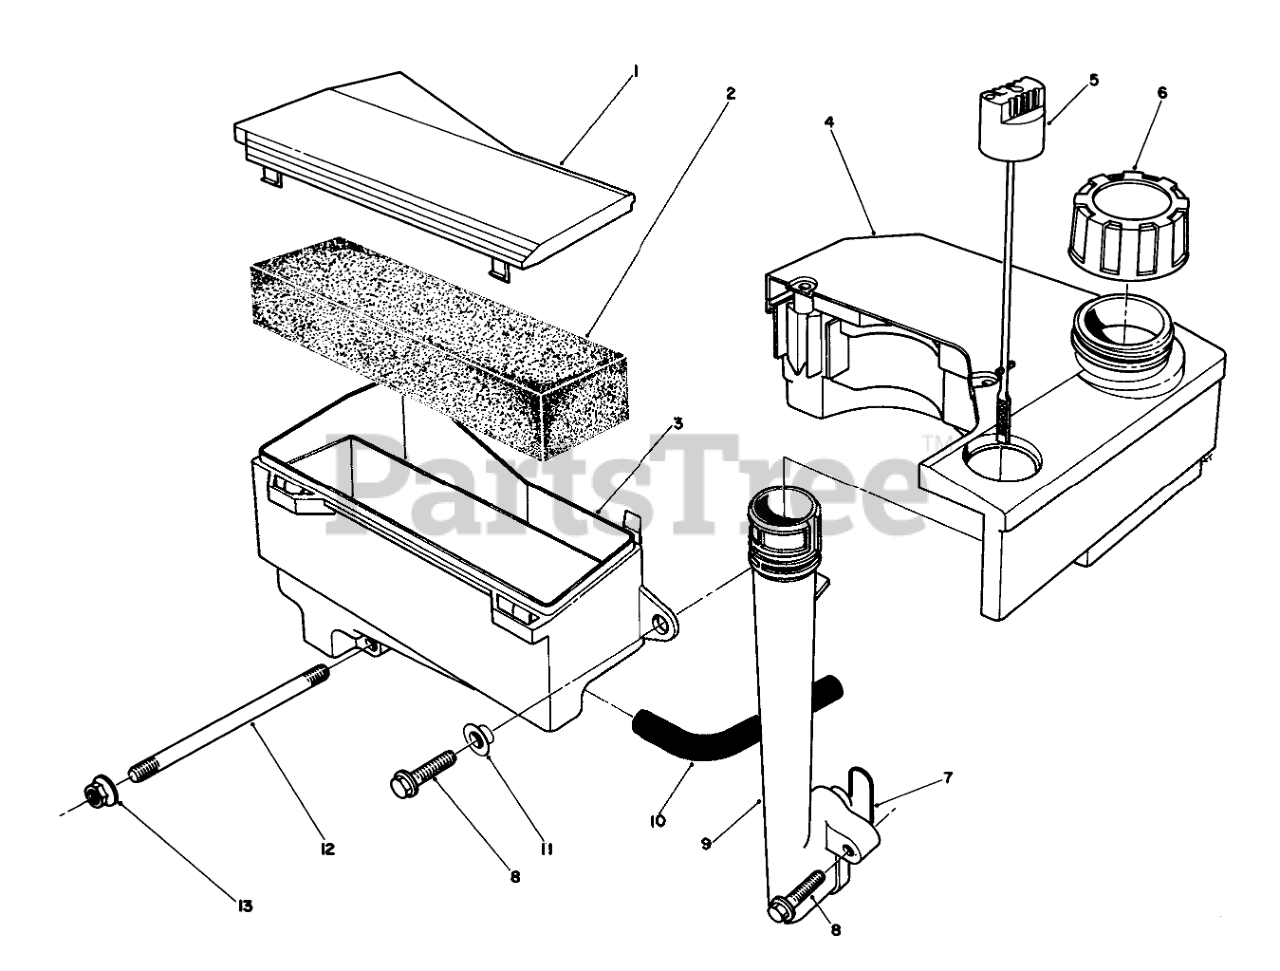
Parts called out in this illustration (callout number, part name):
1	AIR CLEANER CAP
3	Body-Air Cleaner
4	TANK ASM
5	Dipstick
6	GAS CAP ASM
7	O-RING
11	SPACER
12	Stud-Carburetor
